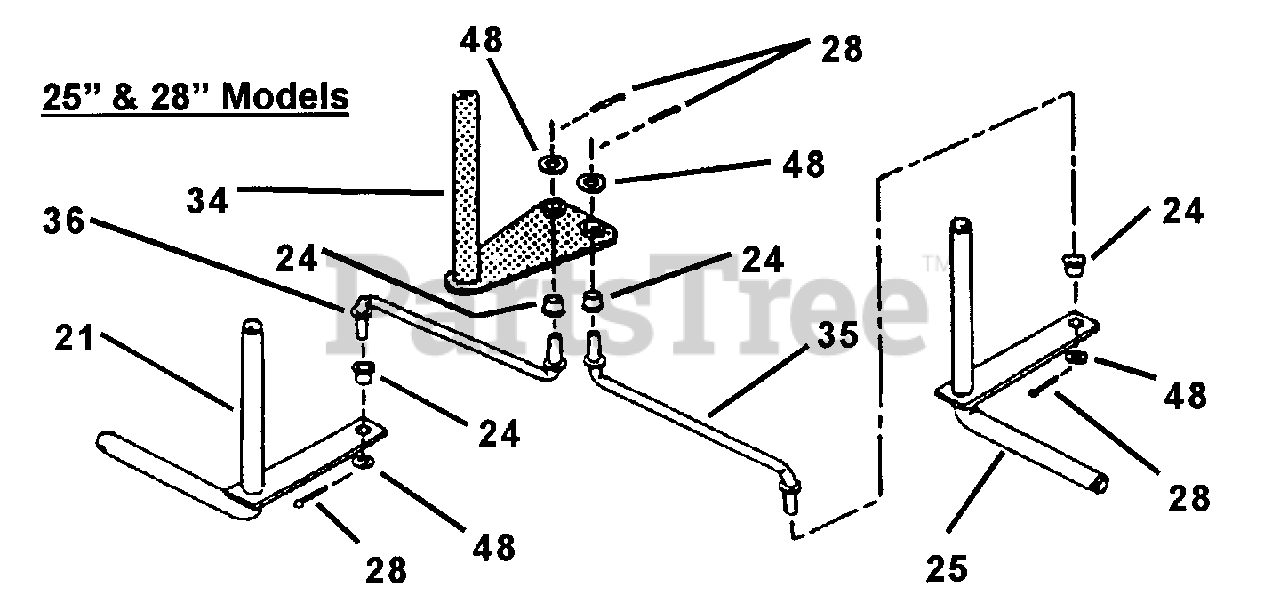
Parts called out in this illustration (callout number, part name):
21	PIN, Narrow King (Right Side)
24	BUSHING
25	PIN, Narrow King (Left Side)
28	COTTER-PIN, 5/32 x 1"
34	SHAFT, Steering (Narrow Front End)
35	TIE-ROD, Left Side
36	TIE-ROD, Right Side
48	WASHER, 3/8" Flat
